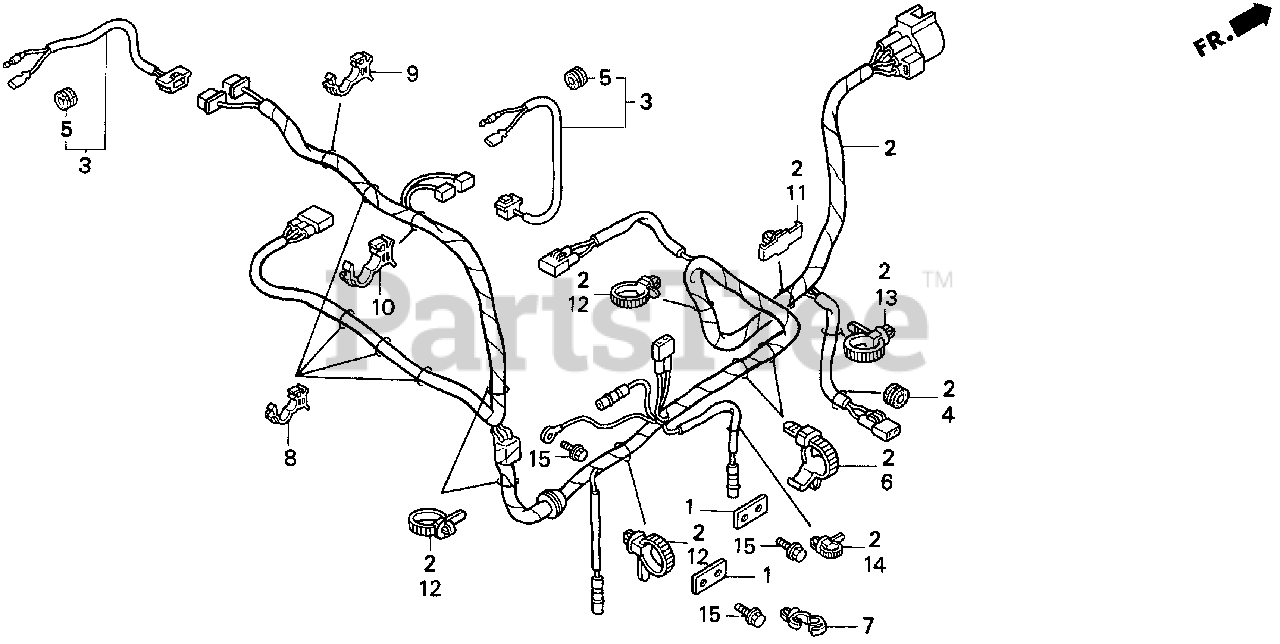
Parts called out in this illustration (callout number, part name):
1	BRACKET, WIRE HARNESS CLIP
2	WIRE HARNESS ASSY., RR.
3	SUB-WIRE, ROPS.
4	RUBBER, HEADLIGHT MOUNTING
5	RUBBER, TAILLIGHT MOUNTING
6	BAND, WIRE HARNESS (WHITE)
7	CLIP, WIRE HARNESS (25MM)
8	CLIP, CABLE (10MM)
9	CLIP, CABLE (15MM)
10	CLIP, CABLE (25MM)
11	CLIP, WIRE HARNESS (BLACK)(HARNESS TAPING)
12	CLIP, WIRE HARNESS (GRAY)
13	BAND, WIRE HARNESS (110MM) (BROWN)
14	BAND, WIRE HARNESS (94MM) (WHITE)
15	BOLT, FLANGE (6X12)
